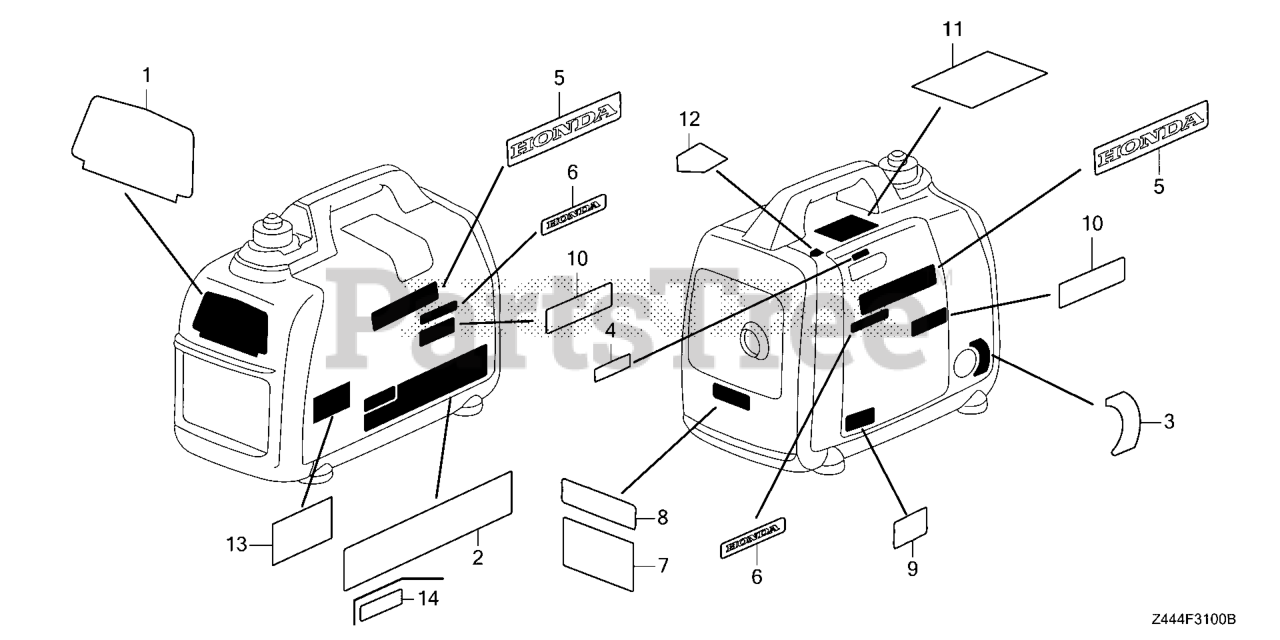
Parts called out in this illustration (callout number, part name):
1	MARK, EMBLEM
2	MARK, CAUTION (AN3)
3	MARK, ENGINE SWITCH
4	MARK, CHOKE
6	MARK, HONDA
7	MARK, EX. WARNING (E)
9	MARK, OIL CAUTION
11	MARK, CPSC (CO CAUTION)
12	MARK, DIRECTION
13	LABEL, SHUTOFF CAUTION
14	LABEL, WARNING
